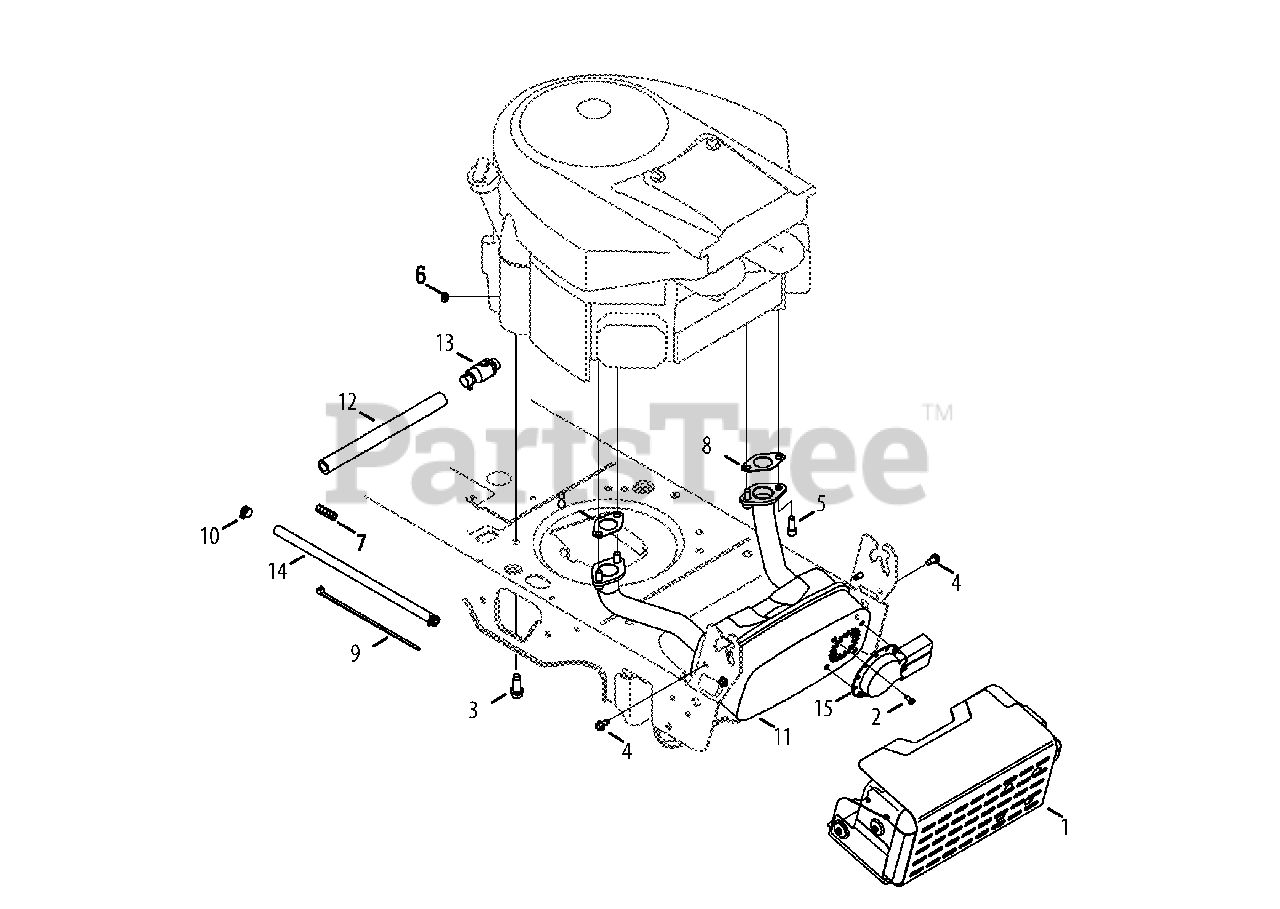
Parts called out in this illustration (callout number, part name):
1	Mulffler Shield Assembly
2	Screw, Indented Washer, #8-18:0.500
3	Taptite Screw, 3/8-16:1.000
4	Taptite Screw, 1/4-20:0.500
5	Socket Head Screw, 5/16-18:.750
6	Sems Nut, 1/4-20
7	Hose Vent
8	Exhaust Gasket
9	Cable Tie, 3/16 x .05 x 7.4
10	Hose Clamp, .490 DIA.
11	Muffler
12	Oil Drain Extension Hose
13	Oil Drain
14	Fuel Hose
15	Long Muffler Deflector, EPA
